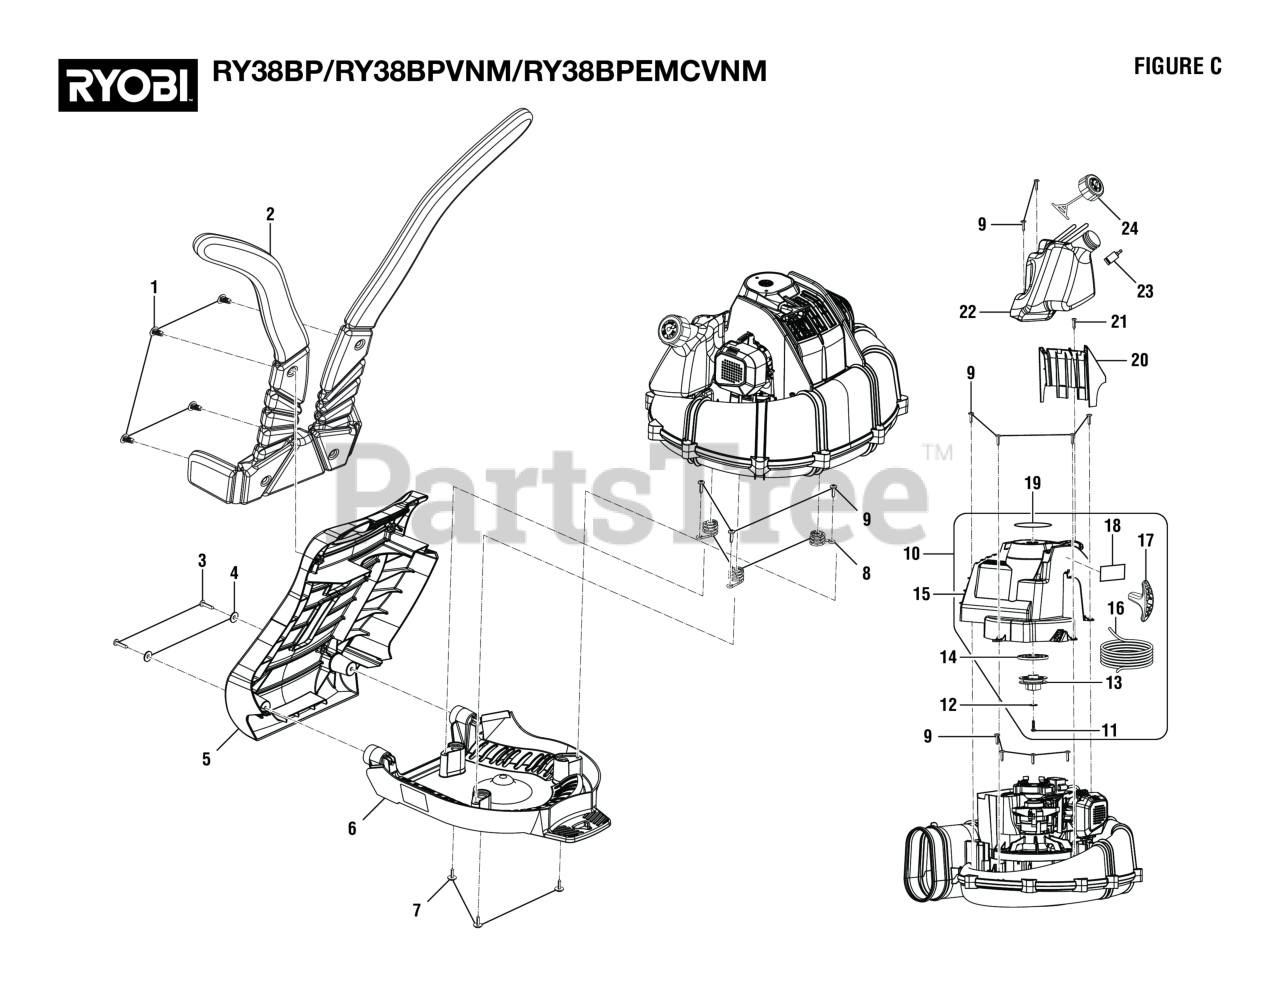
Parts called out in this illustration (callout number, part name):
1	Harness Snap Fastener
3	SCREW (10-14 X 1 in.)
4	Washer (OD16 x ID6.8 x 1.5t)
5	Upper Frame
6	Lower Frame
7	Screw (10-14 x 16 mm)
9	Screw (10-14 x 19 mm, T25 Torx Truss Pan Hd. T.F.)
10	Engine Housing and Starter Assembly
11	Screw (M5 x 14 mm, T25 Torx Pan Hd.)
12	Washer (16OD x 5.3ID x 1.0t)
13	Starter Pulley
14	SPRING & CONTAINER
15	Engine Housing w/Labels
16	STARTER ROPE 42 (PKG)
17	Pulley Handle
18	Mix Ratio Label
19	Logo Label
20	Spark Plug Cover
21	Screw (#10-14 x 3/4 in, T25 Torx Pan Hd. T.F.)
22	Fuel Tank Assembly w/Fuel Lines
23	Fuel Filter
24	Fuel Cap Assembly (Inc. Tether)
